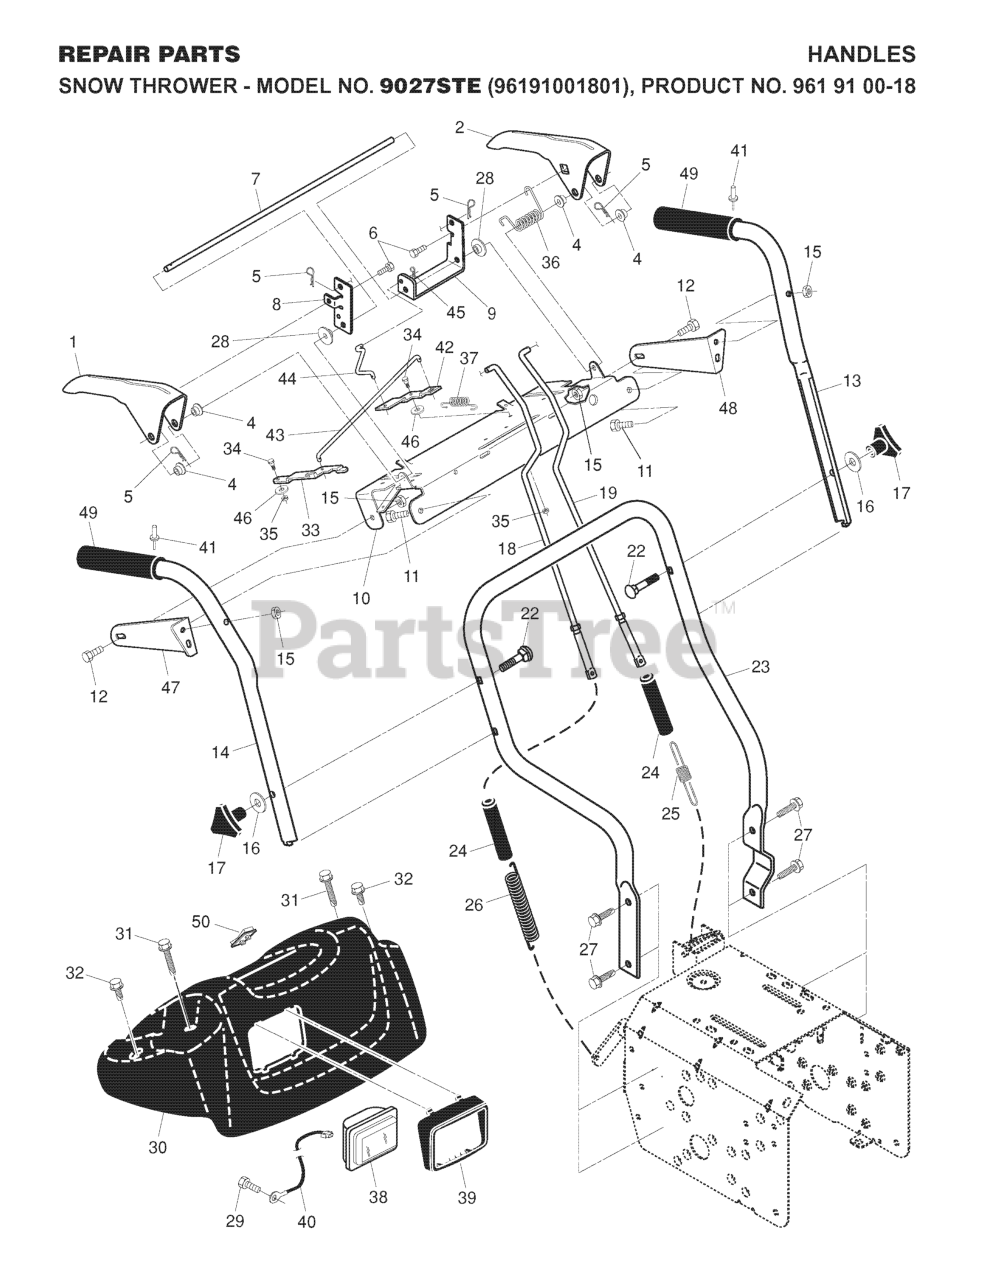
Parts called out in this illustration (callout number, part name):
1	LEVER, AUGER CONTROL, RH
2	LEVER, TRACTION DRIVE CONTROL,
4	BUSHING, FLANGE
5	SPRING RETAINER
7	ROD.INTERLOCK
8	ARM,IMPELLER ROD
9	ARM,TRACTION ROD
10	PANEL.CONTROL
11	HEX BOLT
12	BOLT.FIN.HEX.5/16-18X3/4
13	TUBE.HANDLE.PLOW.LH.PNT
14	TUBE.HANDLE.PLOW.RH.PNT
15	NUT.LOCK.5/16-18
16	WASHER
17	KNOB.HANDLE.3/8.TRI-POINT.BLAC
18	ROD.ASM.IMPELLER
19	ROD.ASM.TRACTION.
22	BOLT 3/8-16 X 2-1/4
23	TUBE.LOWER.HANDLE.24.BLACK
24	SLEEVE, SPRING
25	SPRING, TRACTION DRIVE
26	SPRING, AUGER CONTROL
27	SCREW 3/8-16X1
28	SPACER CONTROL LEVER
29	Screw, Grounding
30	CONSOLE, PANEL
31	SCREW, HEX HD TAPPING #10-24 1
32	SCREW, HEX HEAD, TAPPING
33	LATCH.INTERLOCK
34	BOLT SHOULDER
35	NUT **
36	RP SPRING, TORSION
37	SPRING LATCH
38	HEADLIGHT.HALOGEN.SNOW
39	BEZEL.HEADLIGHT.BLACK
40	HARNESS.WIRE.LIGHT/GRIP.SNOW
41	RIVET.POP.1/8X
42	LEVER.INTERLOCK
43	ROD.LATCH.INTERLOCK
44	ROD.ASM INTERLOCK
45	RETAINER CLIP
46	THRUST WASHER
47	BRKT.PANEL.LH.INT
48	BRKT.PANEL.RH.INT
49	GRIP.HANDLE.HEATED
50	SWITCH.GRIP.HEATED
